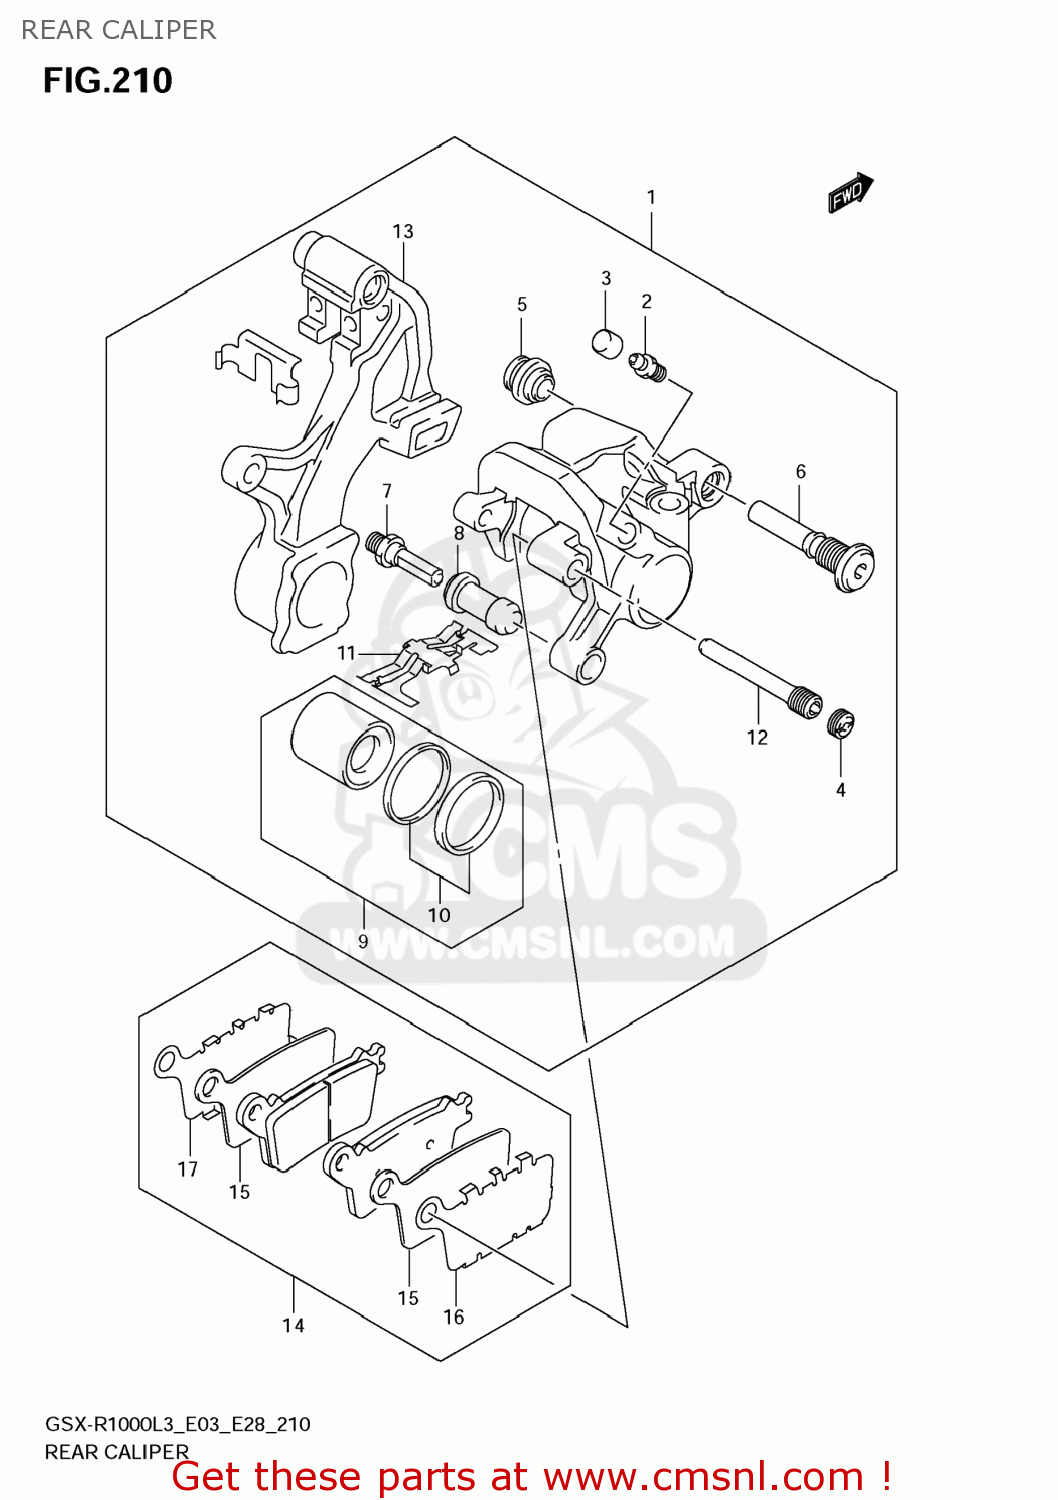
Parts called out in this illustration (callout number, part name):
1	CALIPER ASSY,RR
2	BLEEDER
3	CAP,BLEEDER
4	PLUG,PIN
5	BOOT
6	PIN,BOLT
7	PIN,BOLT
8	BOOT
9	PISTON SET
10	SEAL SET,PISTON
11	SPRING,PAD
12	PIN,PAD
13	BRACKET,RR
14	PAD & SHIM SET (NAS)
15	INSULATOR
16	RETAINER,PAD
17	RETAINER,PAD
